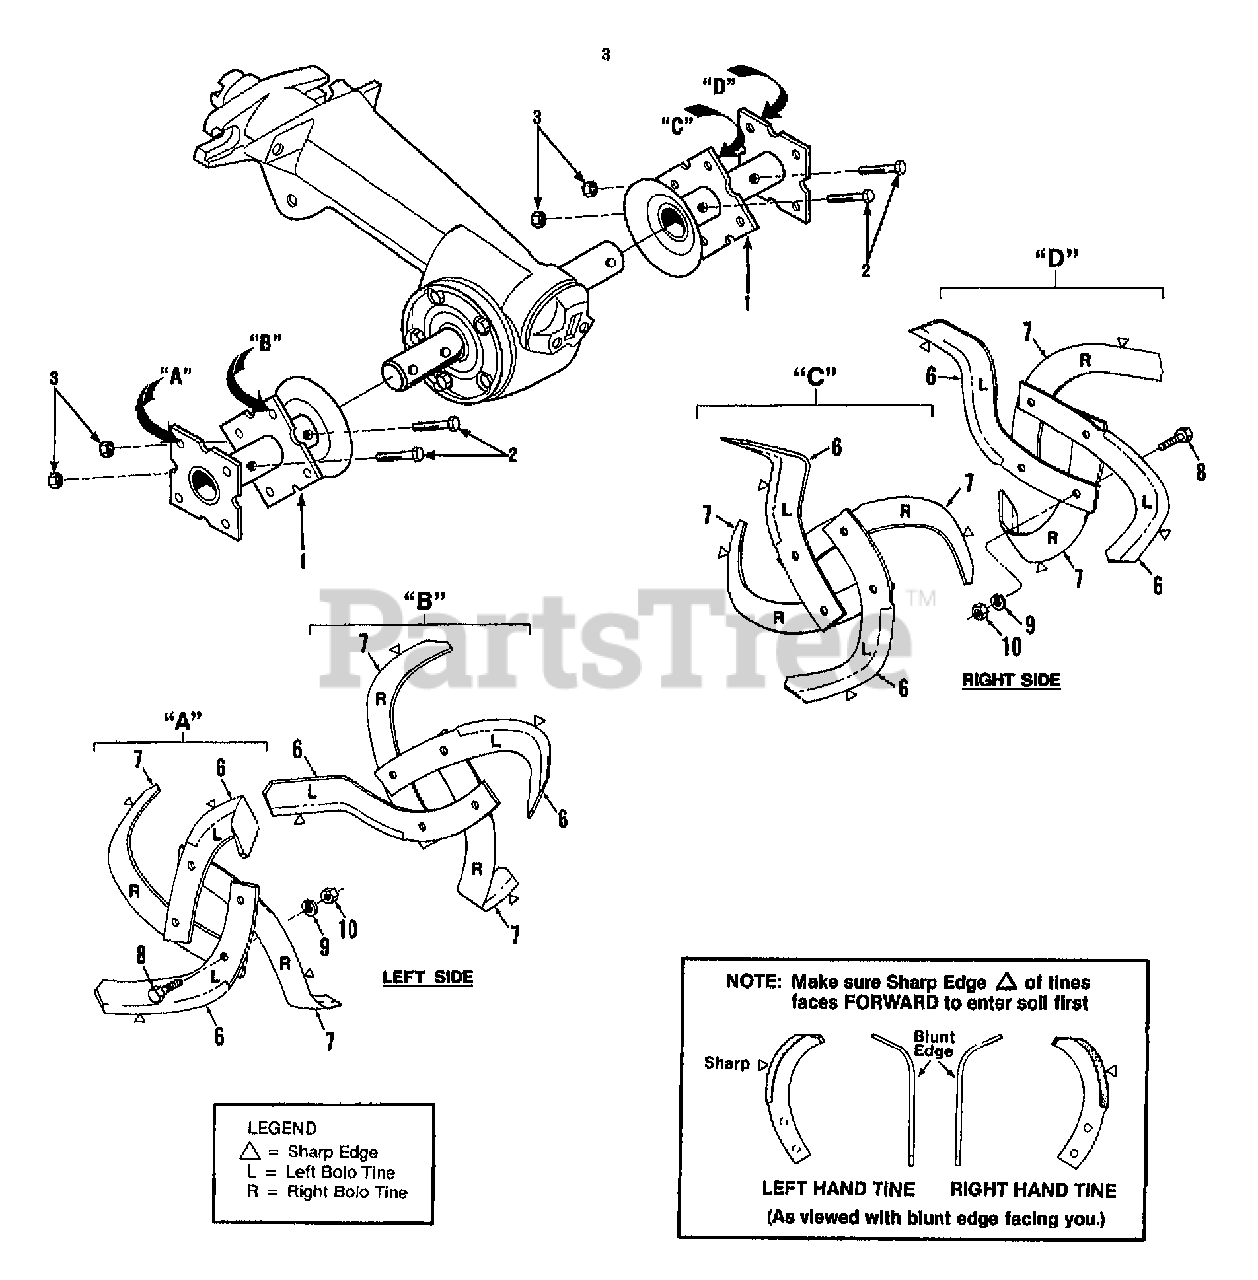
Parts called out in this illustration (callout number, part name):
1	HOLDER-TINE HORSE (RED)
2	SCR-HH 3/8-16X2.00 G8
3	NUT-H/LK 3/8-16
4	THIS REF. NO. NOT USED
5	THIS REF. NO. NOT USED
6	TINE-BOLO LT W/HDW(INCL. TWO EACH OF REF. NO.'S 8,9 AND 10)
7	TINE-BOLO RT W/HDW(INCL. SAME HARDWARE AS REF. NO.6)
8	SCR-HH 3/8-16X1.0 G5 ZP
9	WASHER-LK .375 @ DEPL
10	NUT-HEX 3/8-16 ZP
